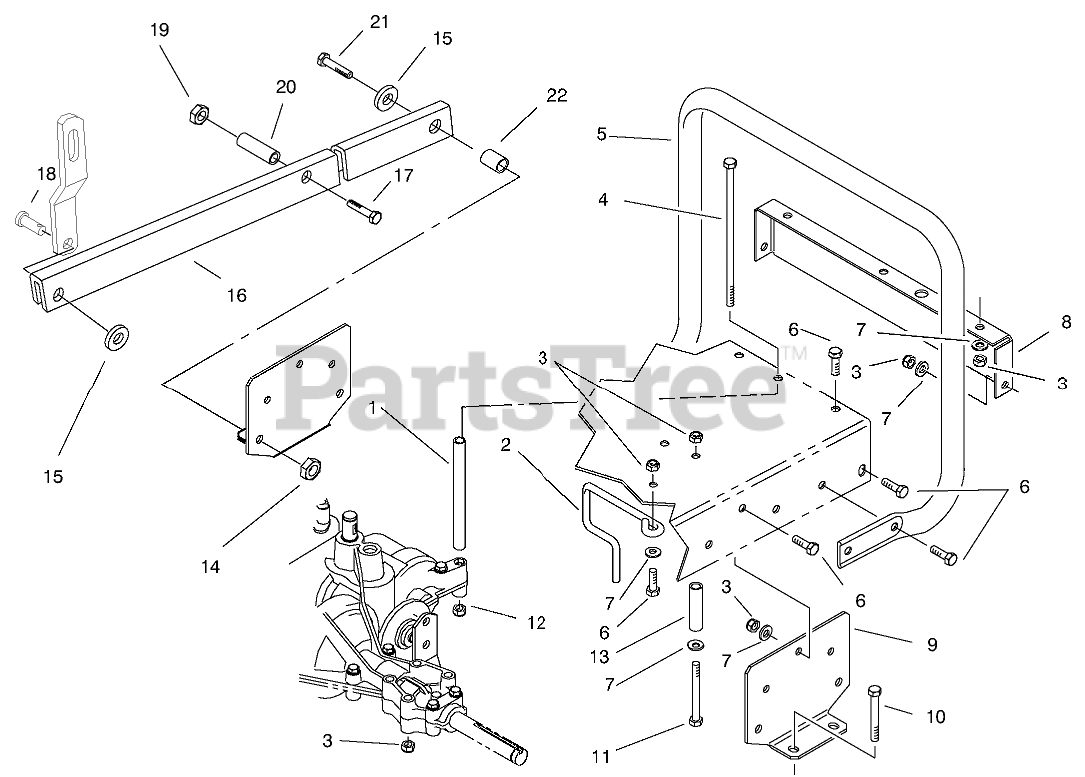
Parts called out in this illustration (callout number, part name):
1	SPACER-TRANSAXLE SUPT
2	GUIDE-ENG BELT
3	NUT-LOCK, NI
4	SCREW-HH
5	STANDBAR
6	SCREW-HH
7	WASHER-PLAIN
8	FRAME - REAR
9	SUPPORT-AXLE
10	SCREW-HH
11	SCREW-HH
12	NUT-LOCK, NI
13	SPACER-SPLIT TUBE
14	NUT-LOCK, NI
15	WASHER-FLAT
16	ARM-RH DECK SUSP.
17	SCREW-HH
18	PIN-CLEVIS
19	NUT-LOCK, NI
20	SPACER-SPLIT TUBE
21	SCREW-HH
22	PIN-SUPT ARM
